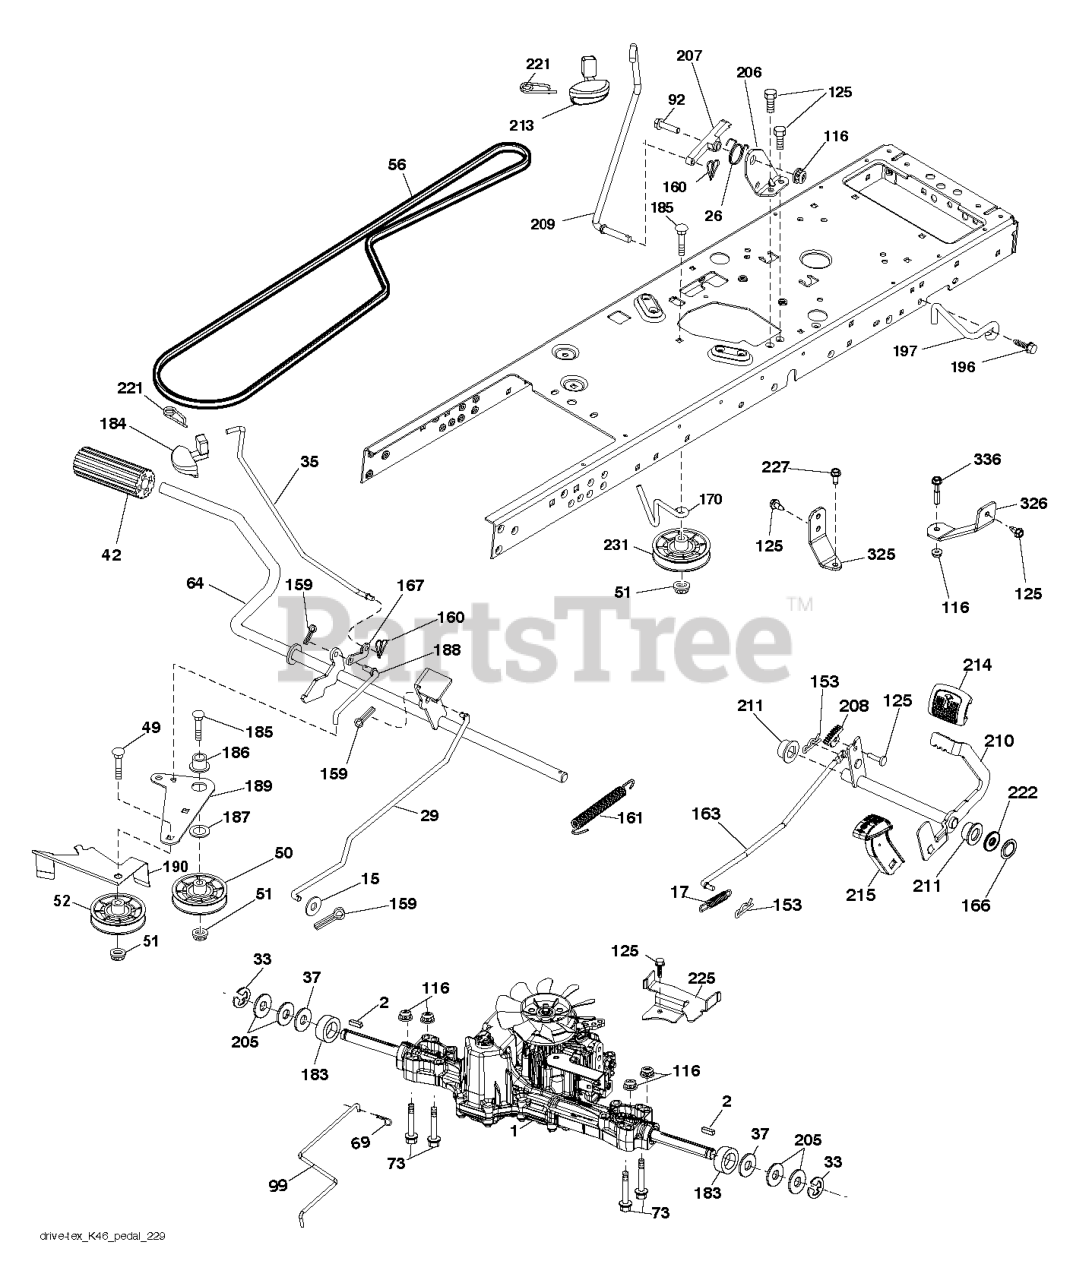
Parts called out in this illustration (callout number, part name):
2	SQUARE KEY
15	WASHER
17	SPRING.BRAKE.K46.GREEN
26	SPRING.RETURN.CRUISE
29	ROD.BRAKE.K46
35	ROD ROD.PARKINGBRAKE.GT.HUSQ/P
37	WASHER.HARDENED
42	PEDAL COVER T
50	IDLER.FLAT.910.OFFSET
51	NUT LOCK FLG 3/8-16 UNC
52	IDLER.V-GROOVE.910.OFFSET
56	V-BELT.MOWER.92.40.42/K46
64	SHAFT.ASM.PEDAL.BRK.CNTR
69	HAIRPIN.SOFT.ZINC.059X1.125
73	BOLT
92	BOLT
99	ARM.PIVOTING.TCRD.GEN2.5.BAGGE
116	NUT LOCK HEX FLANGE 5/16-18
125	SCREW
153	RETAINER M
159	COTTER PIN
160	RETAINER CLIP
161	SPRING, RETURN LT
163	ROD.CONTROL.K57R.K46
166	NUT.PUSH.625
167	LATCH.BRAKE.SPRING
170	KEEPER.CENTER SPAN.1.688
183	SPACER AXLE
184	HANDLE.PARKING.BRAKE.H (BLK)
186	SPACER.RETAINER
187	WASHER 12/32X2X10GA
188	LINK.CLUTCH.GROUND DRIVE.LONG
189	BELLCRANK.GROUND.DRIVE.TEX.
190	KEEPER.BELLCRANK.DRIVE
196	SCREW 3/8-16X1
197	BRKT.42.FCS.CLUTCH.ANTIROTATIO
206	BRACKET.MOUNT.CRUISE.LATCH
207	LATCH.CONTROL.CRUISE.TEX
208	GEAR.SECTOR.CONTROL.CR
209	ROD ROD.CRUISECONTROL.GT.HUSQ/
210	ROCKER.ASM.PEDAL.CONTR
211	BEARING.NYLON
213	KNOB.CONTROL.CRUSIE.HU
214	PEDAL.FORWARD.PAD.TEX
215	PEDAL.COVER.REVERSE.CRD.X428BK
221	RETAINER.SPRING.CLIP.H
222	WASHER 21/32 X 1-1/4 X 10 GA.
225	KEEPER.BELT.TRANSAXLE.K46
227	SCREW.THDROL.5/16-18X3/4.TTY
231	IDLER.V-GROOVE.1.688.OFFSET
325	TORQUE.STRAP.K46.LT.LH
326	BRCKT.PNT.TRQ.STP.46.18TIRE.RH
336	BOLT.5/16-18X1-3/4.FLANGED.HEX
